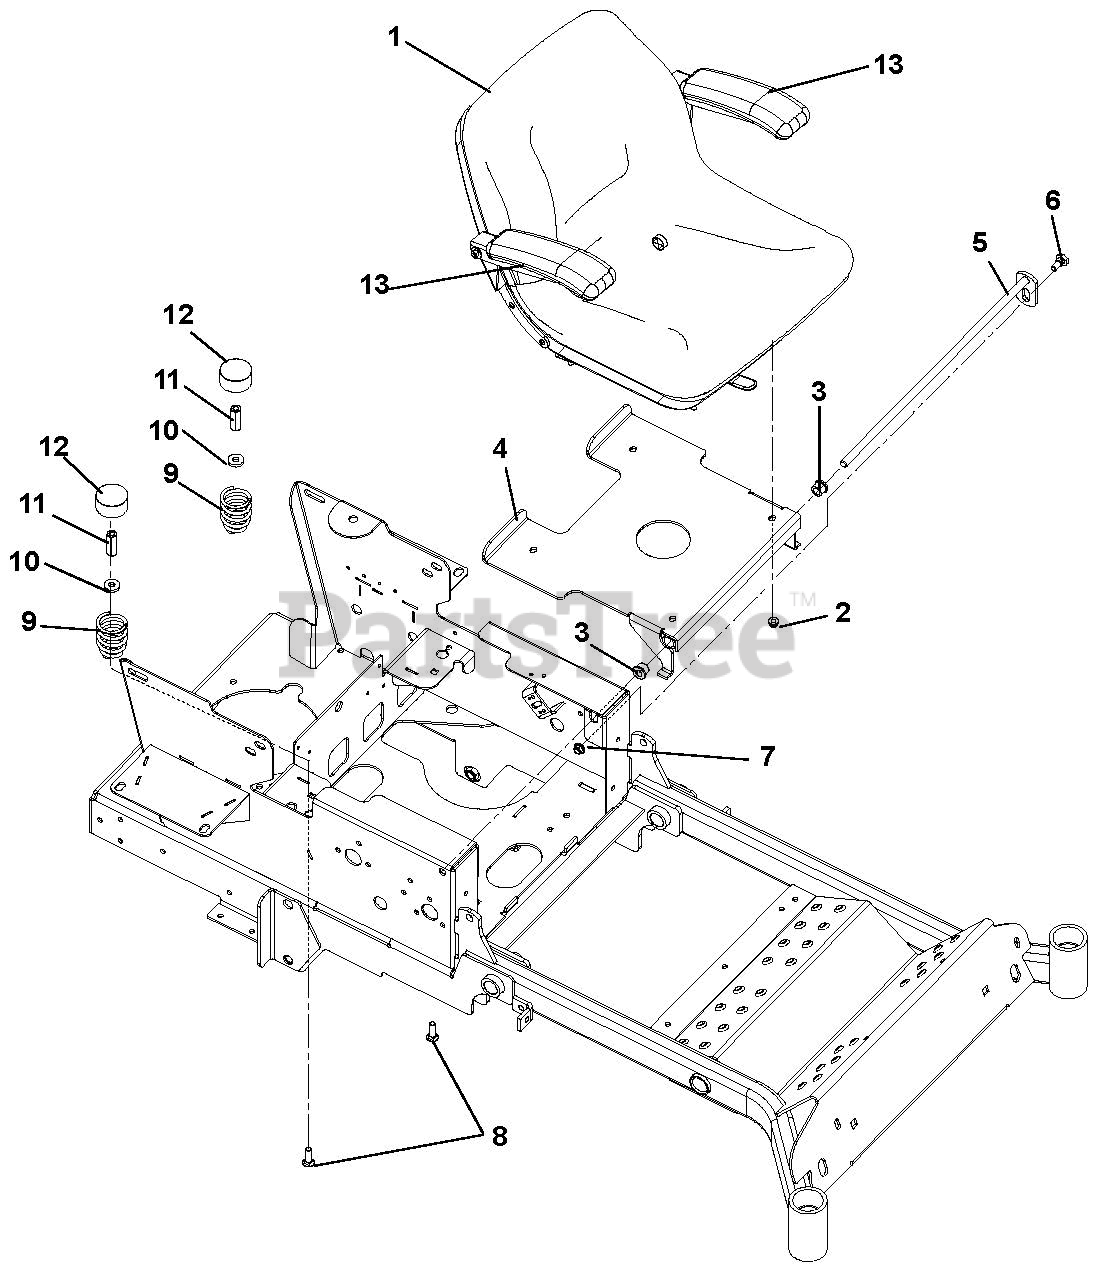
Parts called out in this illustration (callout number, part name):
1	Seat, sk250 cool gray w/arms
2	Nut, Nyloc Flange 5/16-18
3	Bushing, Flange .515 x .750 x .745 x 1.00
4	Weldment, Seat Plate
5	Weldment, Seat Shaft
6	Bolt, Shoulder EP .38-16 x .30 Hex
7	Nut, .38-16 Nyloc Flange
8	Bolt, Round Head Square Neck .38-16 x 1.25 Grade 5
9	Spring, Seat
10	Washer, Flat-Steel .406 x 1.00 x .188
11	Nut, Coupling .375-16 x 1.75
13	Kit, Seat Arm Rests
14	KIT - LH & RH ARM REST REPLACE
